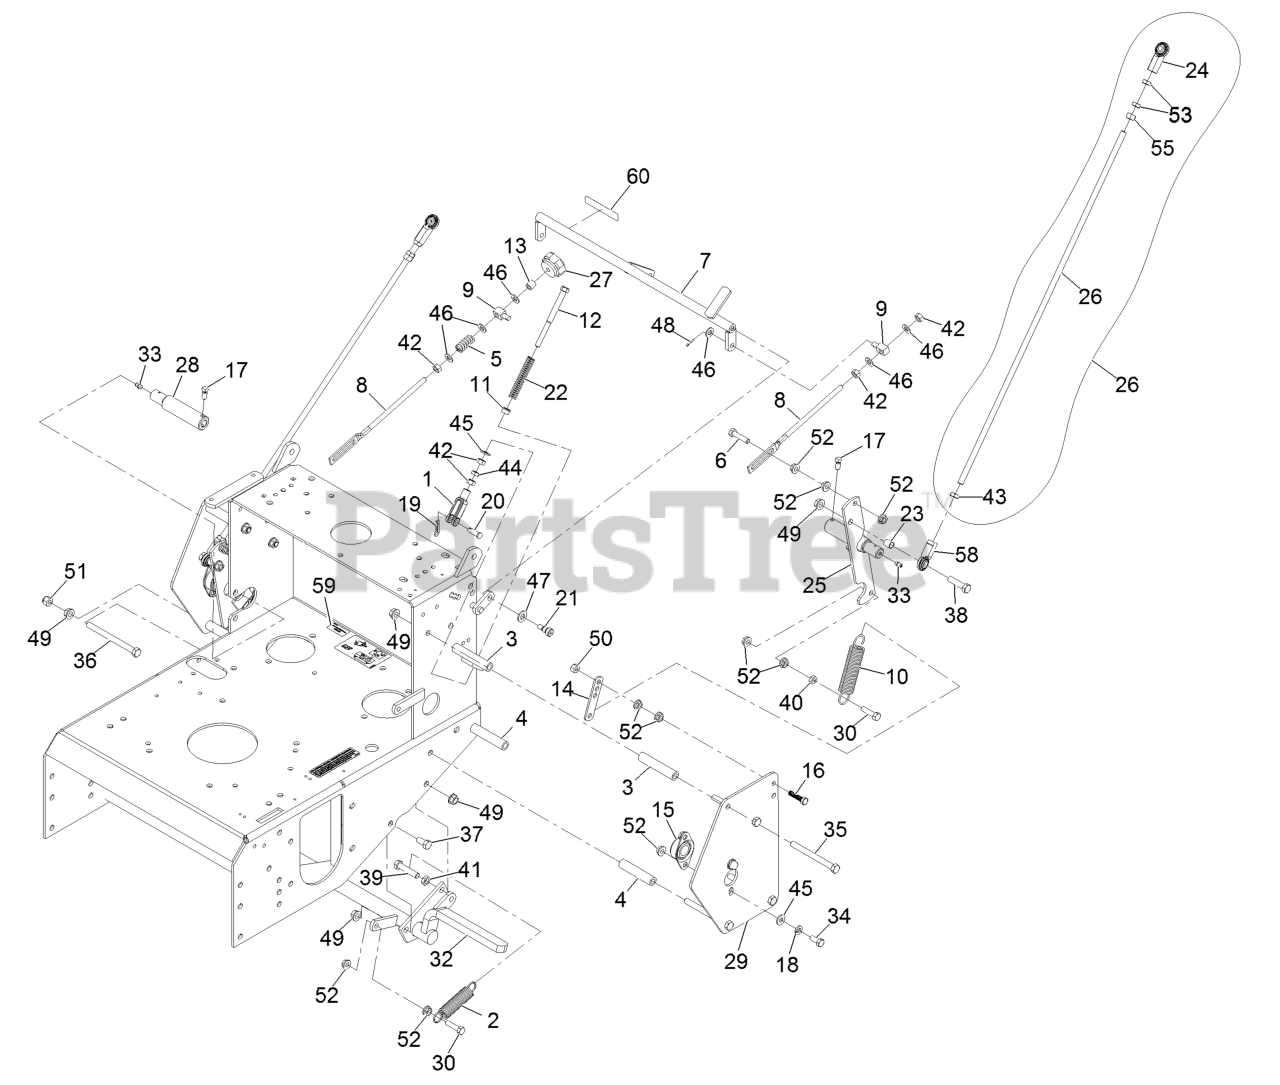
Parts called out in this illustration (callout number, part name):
1	YOKE-ADJUSTABLE
2	SPRING-IDLER
5	SPRING-COMPRESSION
6	SCREW-HH
7	CRANK-CONTROL, SPEED
8	LINK-CONTROL, SPEED
10	SPRING-EXTENSION
11	BUSHING-FLANGED
12	BOLT-RETURN, NEUTRAL
14	TAB-SPRING, EXTENSION
15	BEARING-FLANGE, SIDE
16	BOLT-TAP, HH
17	SCREW-SET
18	WASHER-LOCK
19	PIN-COTTER
20	PIN-CLEVIS
21	SCREW-HSH
22	SPRING,COMPRESSION (NEUT)
23	SPACER-TUBE, PUMP LINK
24	JOINT-BALL, END
25	SHAFT-CONTROL, LH
26	LINKAGE,DRIVE (PLT)
26	DRIVE LINK ASM
27	KNOB-TRACKING
28	SHAFT-CONTROL, RH
29	SHIELD-CONTROL
30	SCREW-HH, SPECIAL
33	FITTING-GREASE
34	SCREW-HH
35	SCREW-HH
36	SCREW-HH
37	SCREW-HH
38	SCREW-HH
39	SCREW-HH
40	NUT-JAM
41	NUT-JAM
42	NUT-HEX
43	NUT-HEX JAM, LH
44	NUT-JAM
45	WASHER-FLAT
46	WASHER-PLAIN
47	WASHER-FLAT
48	PIN-COTTER
49	NUT-HHF, WHIZ
50	NUT-LOCK, NI
51	NUT-LOCK, NI
53	NUT-HJ
55	NUT-HEX
58	JOINT-BALL END, LH
59	Decal-Patent Ttco.Com
60	DECAL-TRACKING ADJUSTMENT
